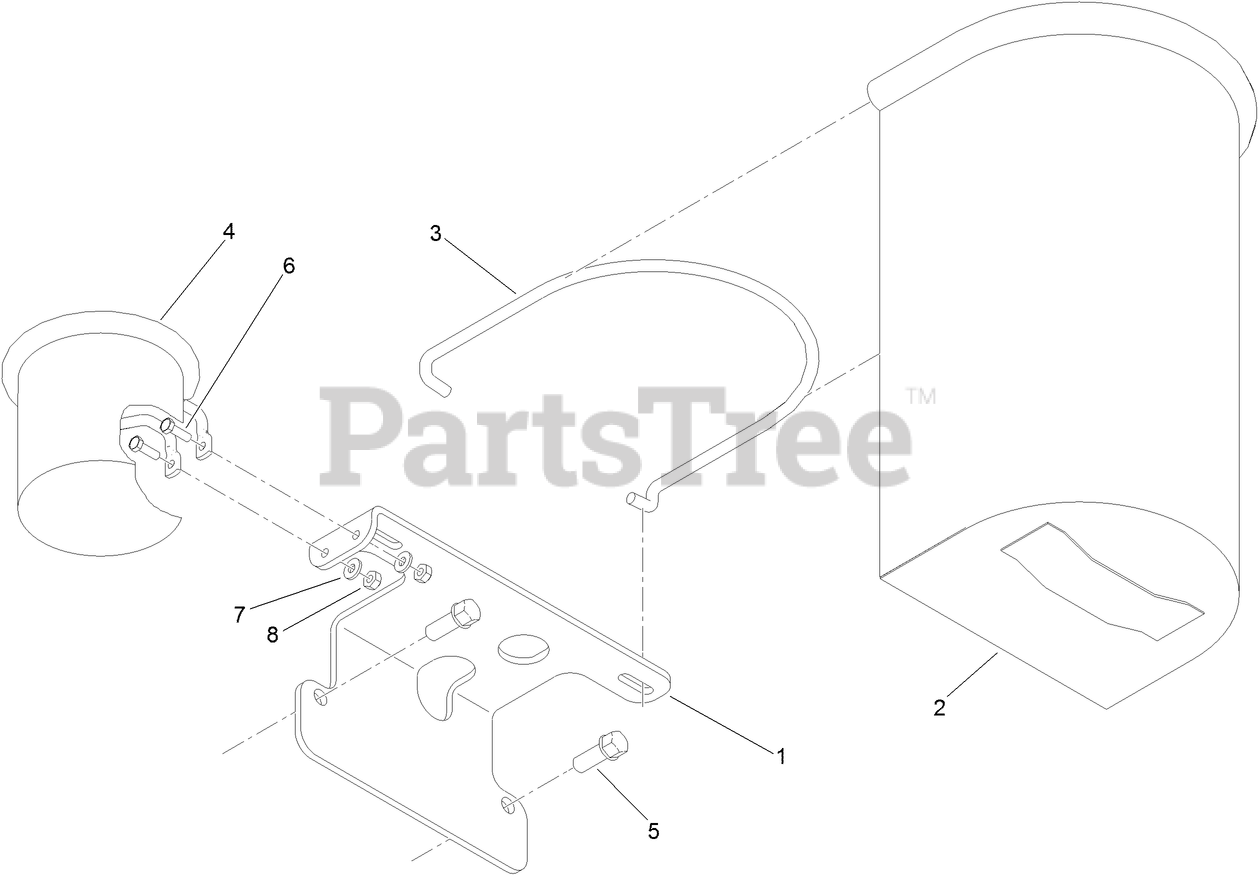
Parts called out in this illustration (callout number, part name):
1	BRACKET-BAG, TRASH
2	BAG-TRASH
3	ROD-BAG, TRASH
4	HOLDER-BAG
5	SCREW-HWH
7	WASHER-FLAT
8	NUT-LOCK, NI
